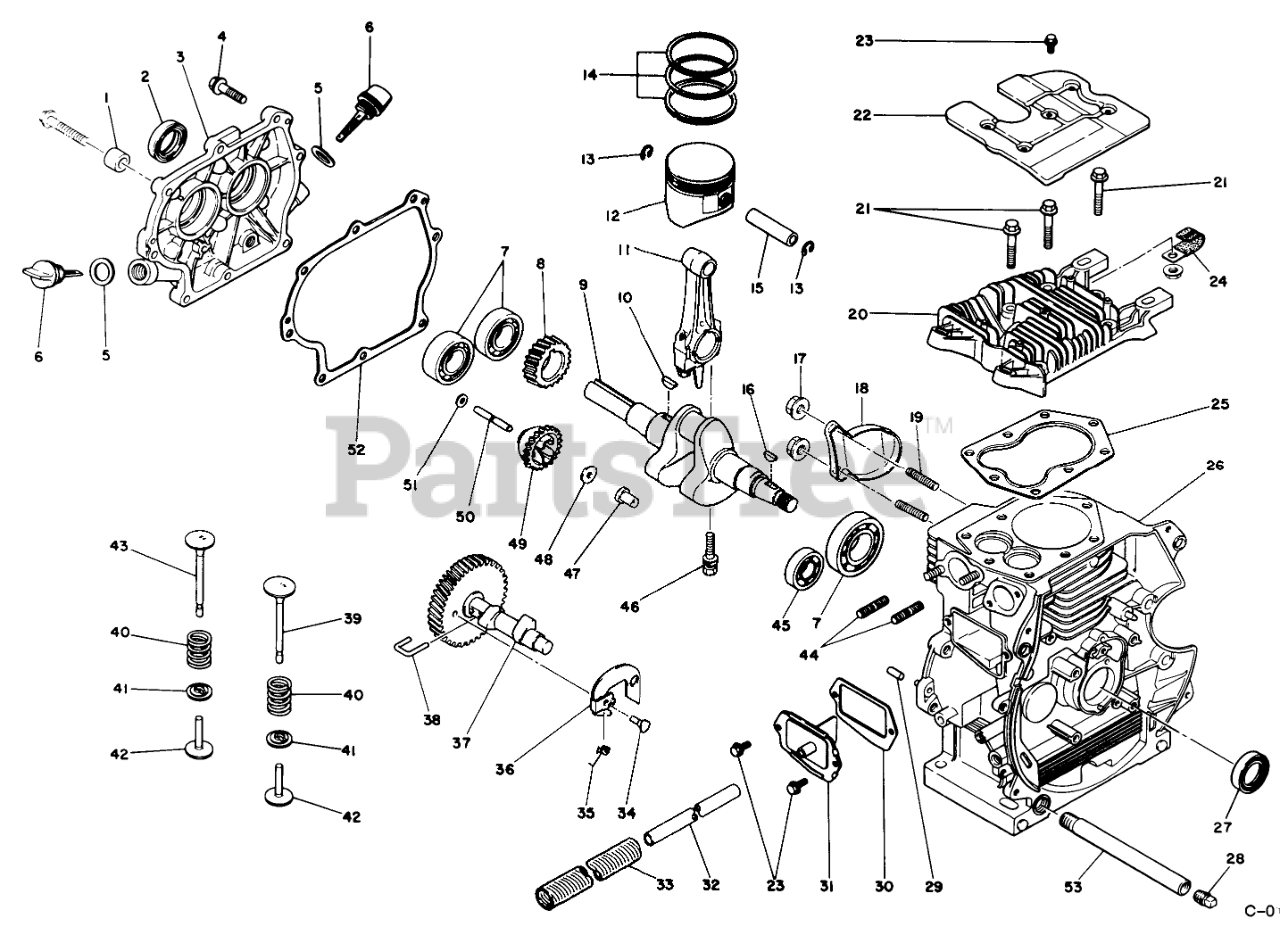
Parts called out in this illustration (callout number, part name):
1	SPACER
2	OIL SEAL
3	CRANKCASE COVER
5	GASKET
6	Gauge-Oil (Incl. Ref. #5)
7	BEARING
8	CRANKSHAFT GEAR
9	CRANKSHAFT
11	Connecting Rod Assembly (Std.) (Incl. Ref #46)
12	Piston Assembly (Std.) (Incl. Ref. #15)
13	PISTON PIN CLIP
14	PISTON RING SET
15	PISTON PIN
18	COVER
20	CYLINDER HEAD
22	COVER-HEAD
24	CLAMP
25	HEAD GASKET
26	Cylinder Block Assembly (Incl. Ref. #19, 29 & 44)
27	OIL SEAL
28	CAP-PIPE
30	GASKET=BRTHR
31	BREATHER VALVE ASM
32	BREATHER TUBE
35	SPRING
36	FLYWEIGHT
37	Camshaft Assembly (Incl.Ref. #34-36 & 38)
39	INT VALVE
40	VALVE SPRING
41	RETAINER VALVE
42	TAPPET
43	EXHAUST VALVE
45	BEARING
46	CONNECTING ROD BOLT
47	SLIDER-GOV
48	SPACER
49	Governor Gear Assembly (Incl. Ref. #47)
50	SHAFT-GOV.
51	WASHER
52	CRANKCASE GASKET
53	DRAIN TUBE
